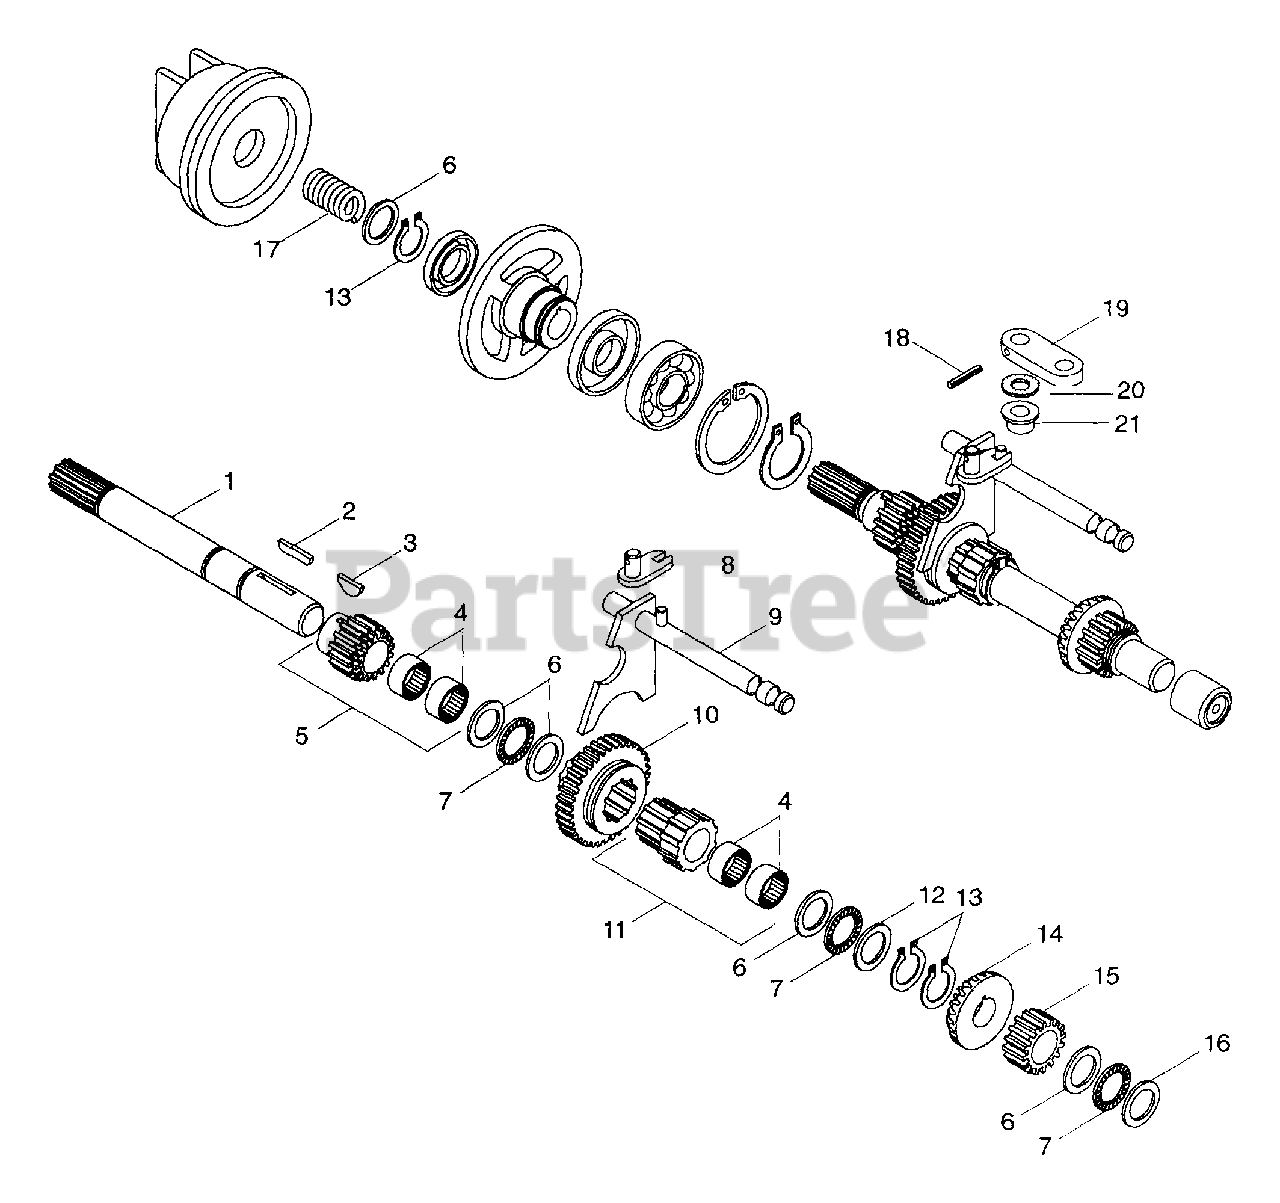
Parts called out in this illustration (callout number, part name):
1	Shaft, Forward Clutch
2	Key, Woodruff .19 x 1.25
3	Key, Woodruff .19 x .63
4	Bearing-Roller .75 x 1.0 x .50
5	Gear and Bearing Assembly
6	Bearing-N-Thrust .752 x 1.24 x .031
7	Bearing-N-Thrust .754 x 1.24 x .078
8	Weldment, Shifter
9	Weldment, Shift Rail
10	Gear, Spur 25 P 10 DP 36 T
11	Gear and Bearing Assembly
12	Washer-Thrust .752 x 1.240 x .062
13	Ring-Retaining-Internal .750 x .042
14	Gear, Bevel
15	Gear, 10 DP 16 Teeth x .750
16	Bearing-N-Thrust .752 x 1.24 x .093
17	Spring-Compression .085 x .80 x 1.00
18	Pin-Roll .187 x 1.000
19	Arm, Shifter
20	Washer-Felt .437 x 1.00 x .031
21	Bushing-Flange .626 x .500 x 1.0
